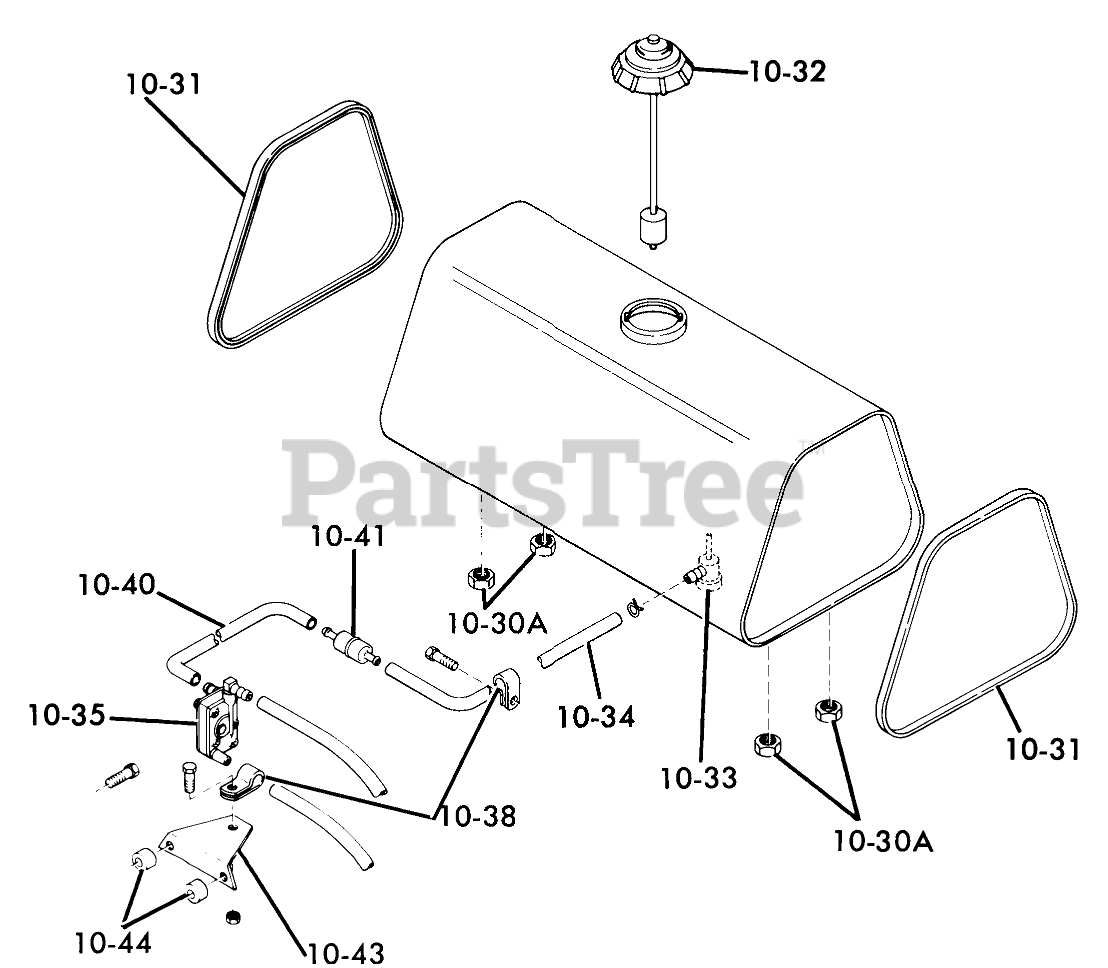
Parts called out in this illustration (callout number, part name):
10-01	Assy-Bracket
10-02	Handle Throttle
10-03	Knob
10-03A	SPACER CLUTCH ARM
10-04	FRICTION WASHER
10-05	WASHER-SPRING DISC
10-06	NUT
10-06A	Washer-3/8
10-07	Rod-Throttle
10-07A	Rod-Throttle
10-08	BALL JOINT ASSY R
10-09	Assy-Bracket
10-10	HANDLE
10-10	Assy-Bracket
10-12	FRICTION WASHER
10-13	WASHER-SPRING DISC
10-14	CABLE CHOKE CONTROL
10-14	CABLE-CHOKE CONTROL
10-16	CLIP BOWDEN WIRE
10-17	THROTTLE CONTROL CLP
10-20	Bracket
10-20	ASSY-MUFFLER
10-21	ASSY-MUFFLER CLAMP
10-22	Nipple
10-22A	NIPPLE-EXHAUST 1X4
10-23	Nipple 2 1/2 in. Long
10-24	Nipple 5 in. Long
10-25	ELBOW
10-26	Fitting Exhaust RH
10-27	TUBE-INLET
10-30	Fuel Tank
10-30A	Flanged Nut
10-31	Edge Trim
10-32	GAUGE CAP
10-33	FILTER & VALVE ASSY
10-34	Fuel Line 62
10-35	Pump Fuel
10-36	Coupling
10-37	FITTING STRAIGHT
10-38	CLAMP-HOSE
10-40	Hose
10-41	Filter
10-43	Bracket
10-44	Spacer
